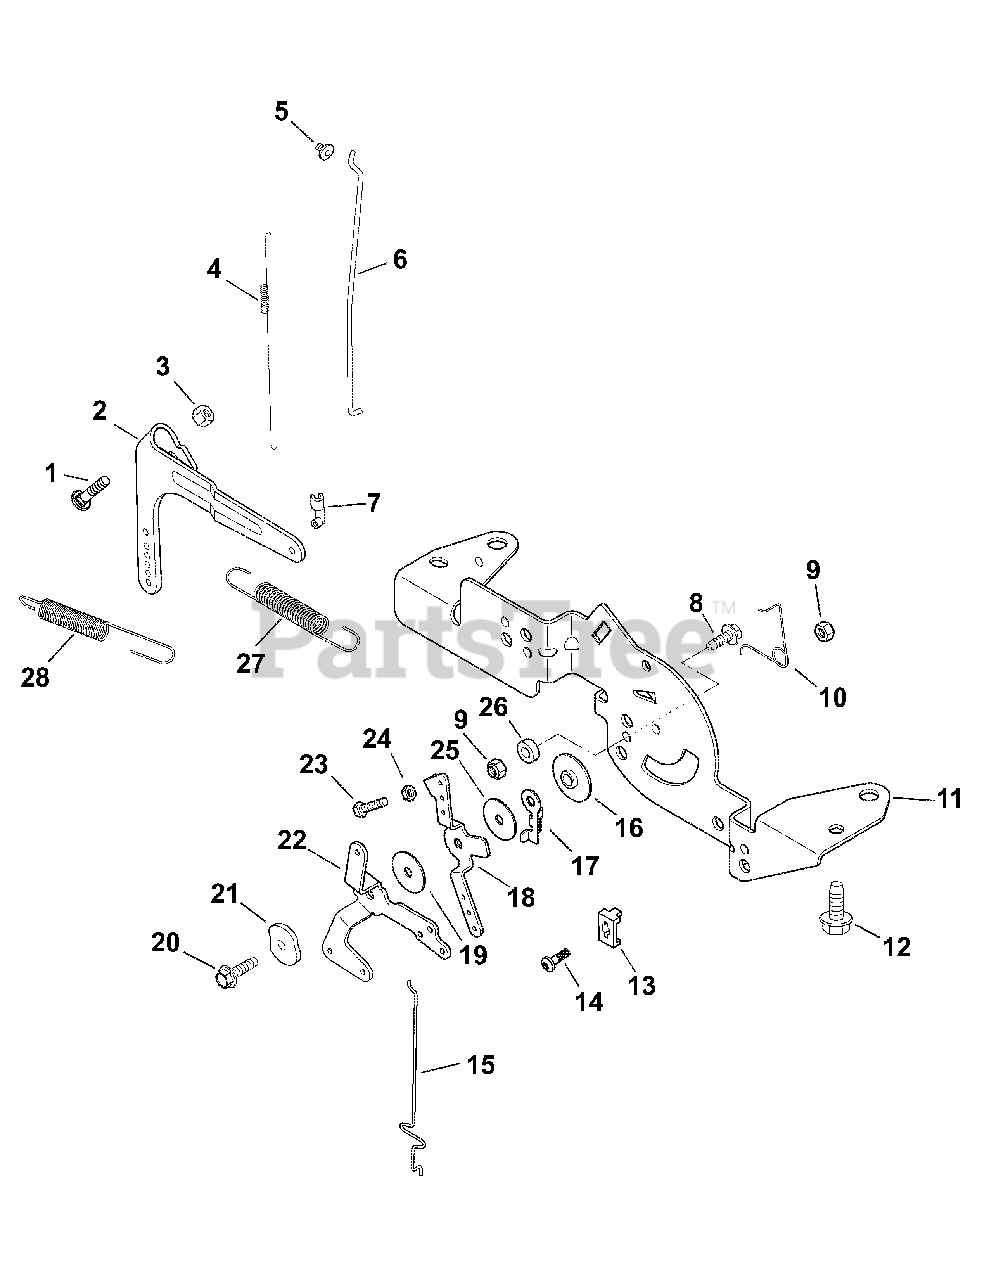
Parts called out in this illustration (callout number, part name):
1	Bolt, RD HD SQ Neck M6 x 1.0 x 25
2	Lever, Governor
3	Nut, FLG M6 x 1.0
4	Spring, Linkage
5	Bushing, Linkage Retaining
6	Linkage, Throttle
7	Bushing, Throttle Linkage
8	Screw, FLG THD FRM M5 x 0.8 x 16
9	Nut, Lock M5 x 0.8
10	Spring, Choke Return
11	Bracket, Control
12	Screw, FLG THD FRM M6 x 1.0 x16
13	Clamo, Cable
14	Screw, LBD THD FRM M5 x 0.8 x 16
15	Linkage, Choke
16	Spacer, Control Assembly
17	Lever, Throttle Actuator
18	Lever, Throttle Control
19	Washer, Flat 5.5 MM
20	Screw, FLG THD FRM M5 x 0.8 x 20
21	Washer, Spring 1/4"
22	Lever, Choke
23	Screw, Slt Hd Cap M4 x 0.7 x 25
24	Nut, M4 x 0.7
25	Washer, Flat 5 MM
26	Spring, Governor
27	Spring, Governor
